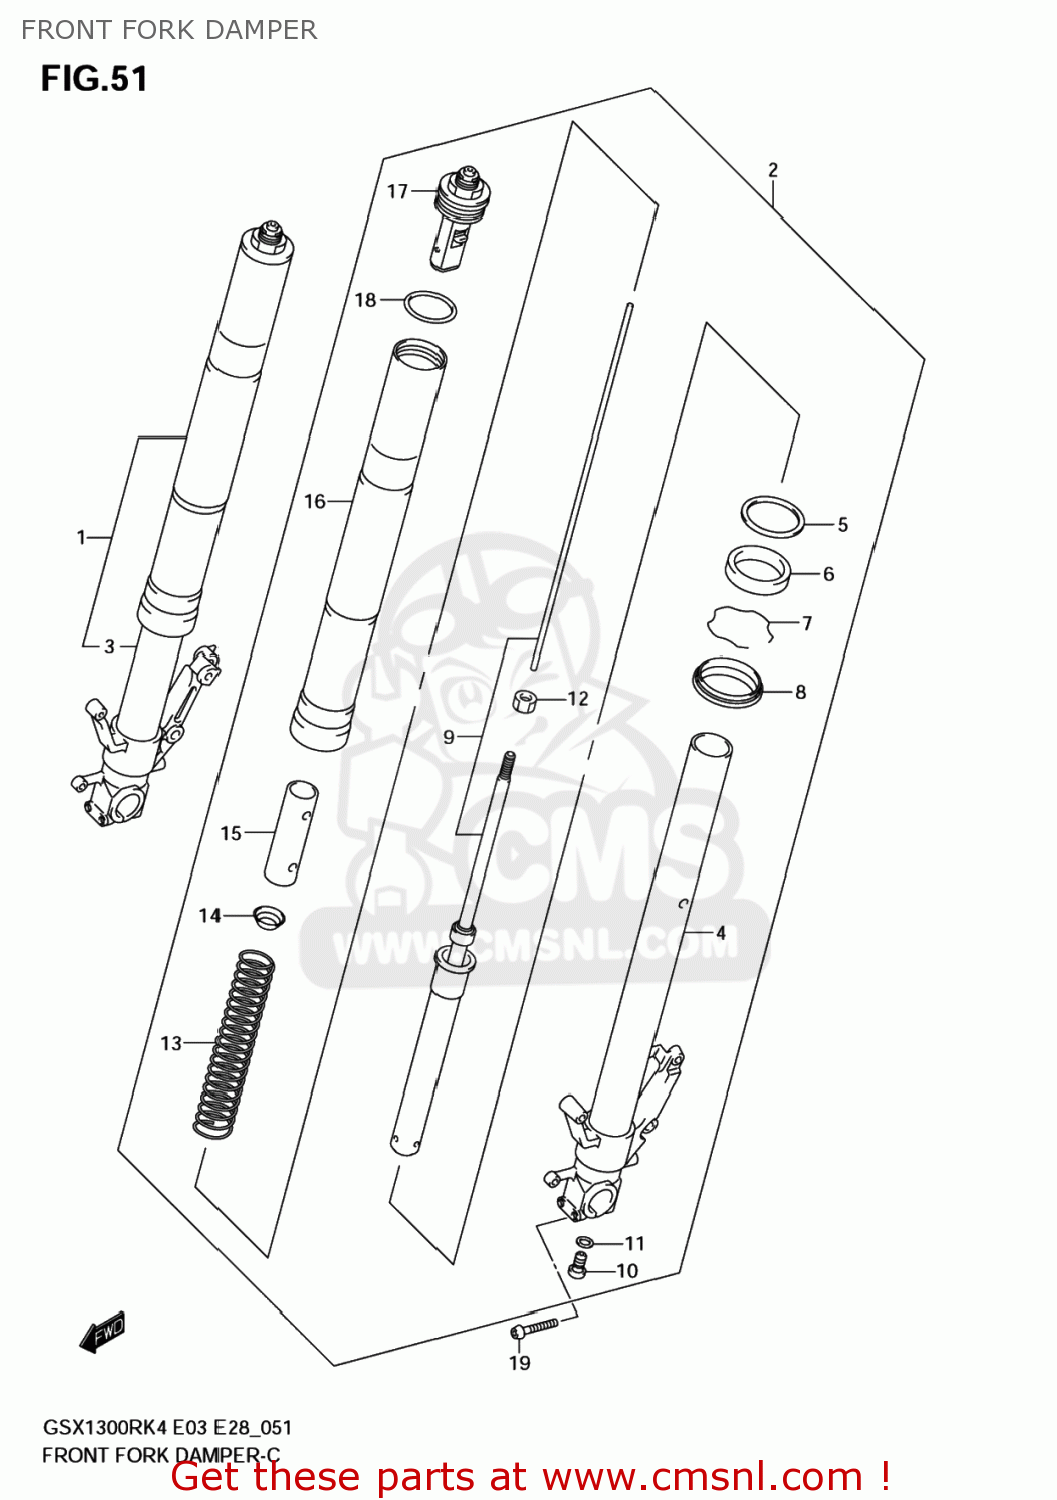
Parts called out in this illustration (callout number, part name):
1	DAMPER ASSY,FR FORK,R
2	DAMPER ASSY,FR FORK,L
3	TUBE,INNER,R(BLACK)
4	TUBE,INNER,L(BLACK)
5	WASHER
6	SEAL,OIL
7	RING,STOPPER
8	SEAL,DUST
9	CYLINDER
10	BOLT,OIL LOCK PIECE,12X22
11	GASKET,CYLINDER (NAS)
12	NUT
13	SPRING,FR
14	GUIDE,SPRING
15	SPACER,SPRING
16	TUBE,OUTER(BRONZ)
17	CAP,FR FORK
18	O RING
19	BOLT(8X45)
